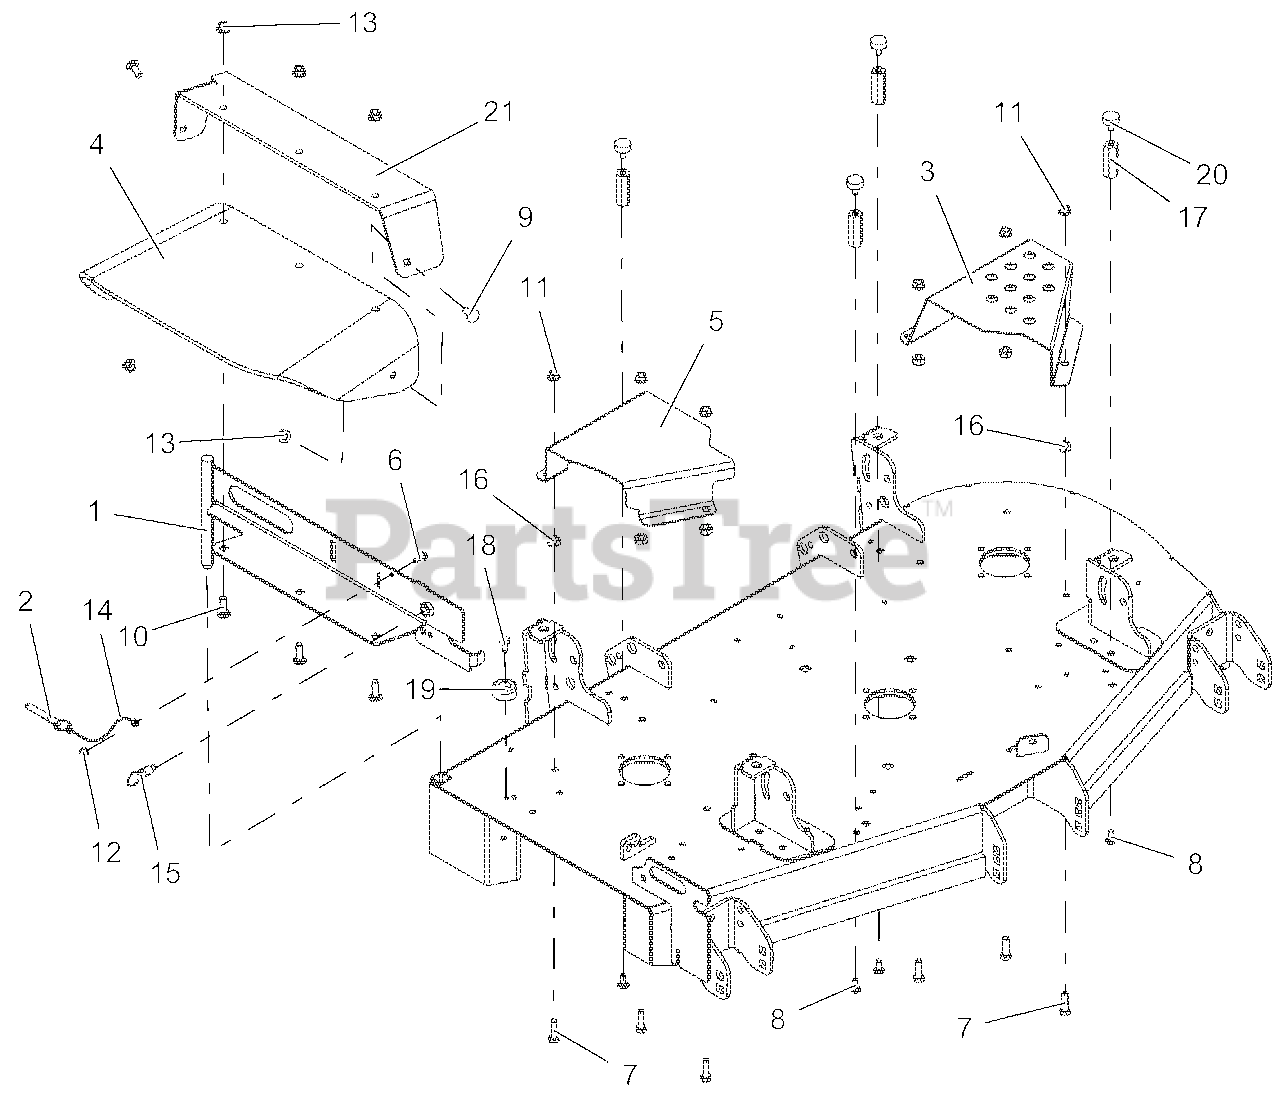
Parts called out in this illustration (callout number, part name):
1	WLDMT, 44"-48" DISCH CHUTE MTG-RED
2	PIN, SPRING BALL .375 OD X 1.50
3	GUARD, 44-52" LH DECK BELT-BLACK
4	CHUTE, RUBBER DISCHARGE
5	GUARD, 48"-52" RH DECK BELT-BLACK
6	BLT-HEX .25-20X.75 GR5 YWZC
7	BLT-HEX .38-16X1.25 GR5 YWZC
8	BLT, RDHDSQNK .31-18X.75 LOCTITE
9	BLT-RDHDSQNK .38-16X1.00 G5 YWZC
10	BLT-RDHDSQNK .38-16X1.25 G5 YWZC
11	@NUT-SPNLK-FLG .375-16 YWZC
12	NUT, LK-TOP-FLG .25-20 YWZC
13	NUT-LK-NYL-FLG .38-16 YWZC
14	CABLE, 6.0 LANYARD, NYLON
15	PULL PIN,.50-13THDX.310 PLNGR
16	NUT-HEAVY HEX .38-16 YWZC
17	NUT, .31-18 X 2.25 LG COUPLING
18	SCR-TAP .31-18X.75 HWH TR YWZ
19	BUMPER, RECESSED 1.50 X .63 W/.31 HOLE
20	BUMPER, RUBBER
21	DISCHARGE CHUTE SUPPORT W/SAFETY DECAL-RED
